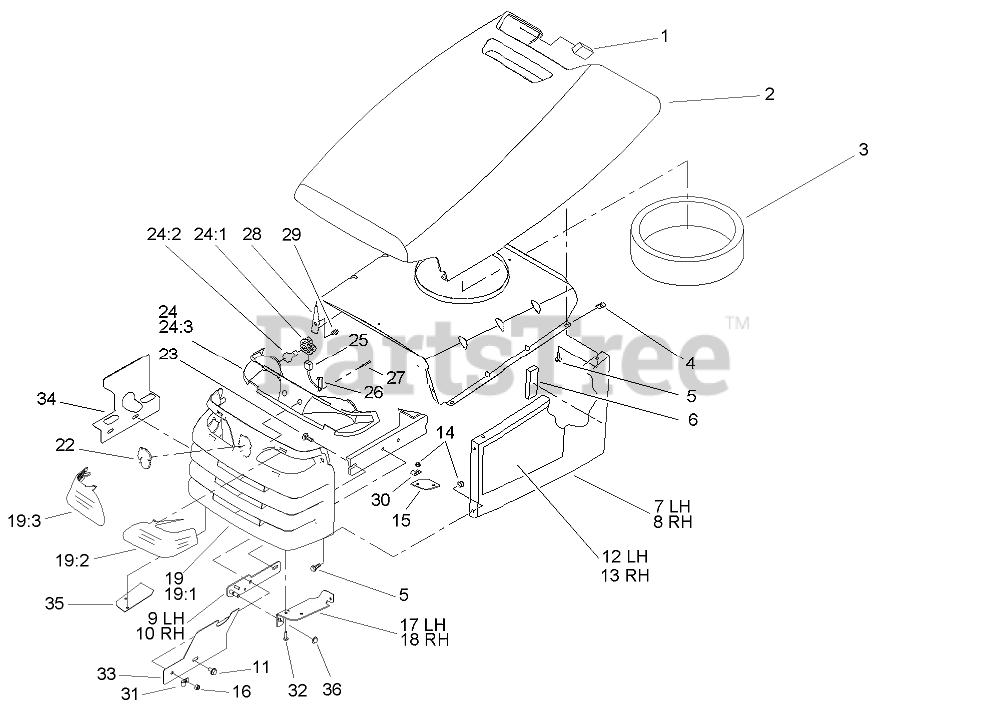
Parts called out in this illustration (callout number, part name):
1	FOAM-HOOD
2	HOOD ASM
3	SEAL-AIR INLET, TWIN
5	SCREW-HWH
6	FOAM-SIDEPANEL
7	HOOD-SIDE, LH
8	HOOD-SIDE, RH
9	BRACKET-HINGE, LH
10	BRACKET-HINGE, RH
11	SCREW-HWHTF
12	DECAL-HOOD, LH
13	DECAL-HOOD, RH
14	NUT-LOCK, HHF
15	HINGE-HOOD
16	NUT-LOCK, NI
17	BRACKET-HOOD, HINGE, LH
18	BRACKET-HOOD, HINGE, RH
19	Grille ASM
19:1	GRILLE
19:2	LENS-LH
19:3	LENS-RH
22	EMBLEM
23	SCREW-CARR
24	REFLECTOR AND LAMP ASM
24:1	SOCKET-HEADLIGHT
24:2	BULB
24:3	REFLECTOR
25	HARNESS-WIRE, HEADLIGHTS
26	TIE-CABLE
27	SCREW
28	BAFFLE-HOOD, UPPER
29	SCREW-PLASTITE
30	CLAMP-R
31	CLAMP-R
32	SCREW-HH
33	HEAT-SHIELD, LH
34	HEAT-SHIELD, RH
35	BRACKET-HEATER
36	RETAINER-PUSH ON
